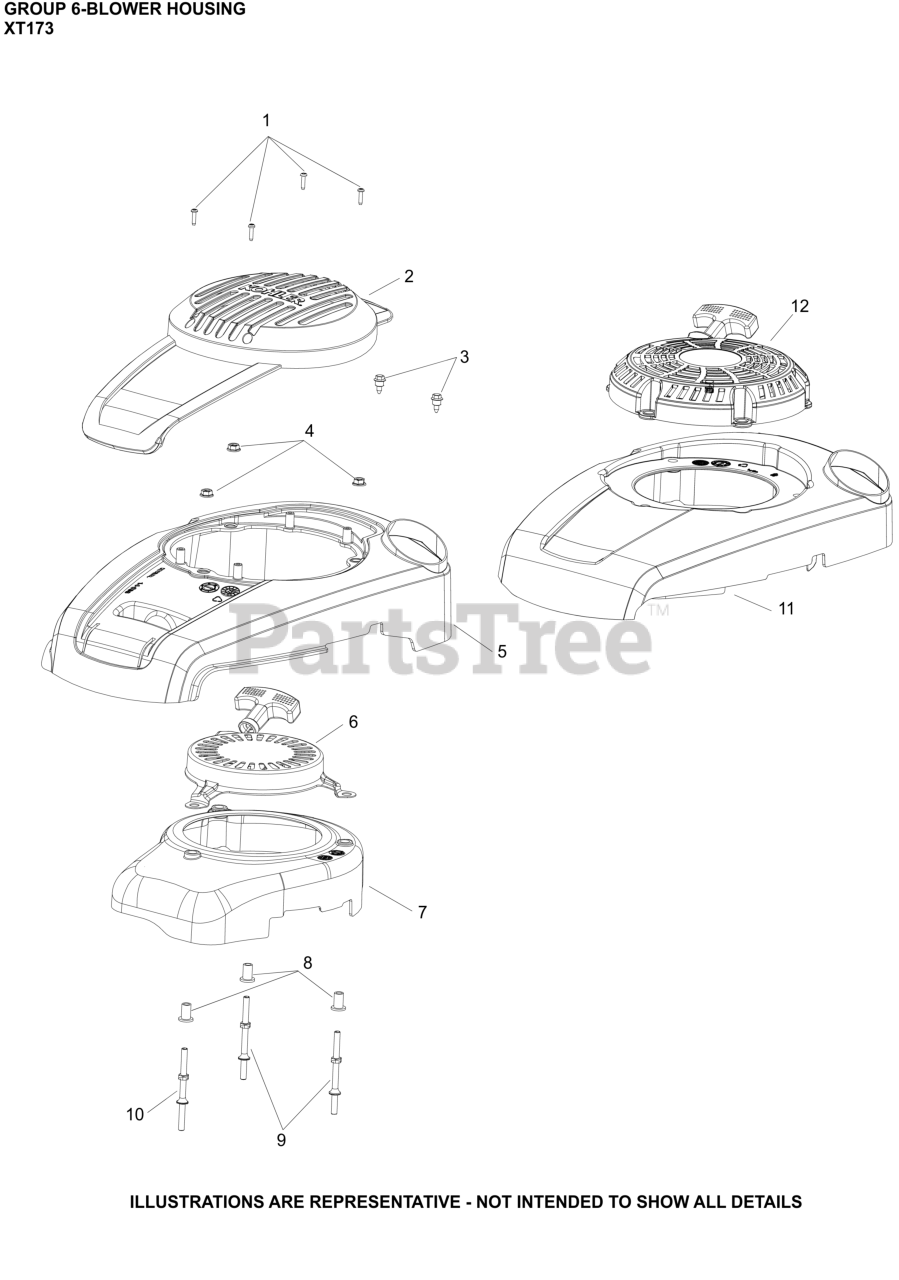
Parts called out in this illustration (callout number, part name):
4	NUT, HEX FLANGE (M6) - USE 14 100 16-S
9	STUD-USE 14 072 26-S
10	STUD-USE 14 072 25-S
11	COVER, ENGINE
